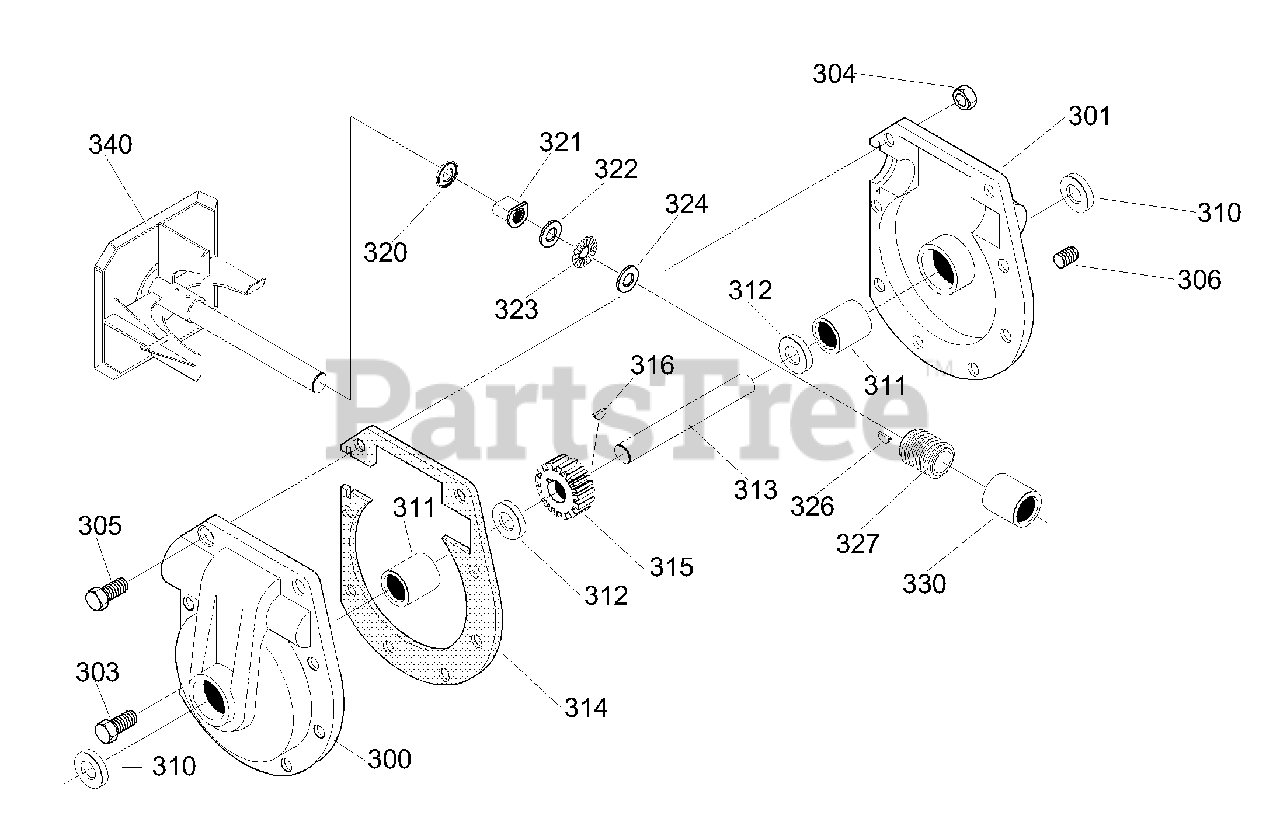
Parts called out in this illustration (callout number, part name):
300	CASE, GEAR RH
301	CASE, GEAR LH
303	SCREW 5/16-24X1.00
304	NUT, 5/16-24 HEXWDFLLK
305	SCREW, 5/16-24X1.50
310	SEAL, OIL
311	BEARING, SLEEVE
312	FLATWASHER
313	SHAFT, AUGER OUTPUT 25"
314	GASKET, GEAR BOX
316	KEY, WOODRUFF #91
320	RING, QUAD
321	BEARING, FLANGE
322	FLATWASHER .752X1.24X.093
323	BEARING, ROLL
324	FLATWASHER .752X1.24X.093
326	KEY, HI-PRO 606
330	BRING, SLEV .752IDX.88ODX.755
340	IMPELLER, ASSY
